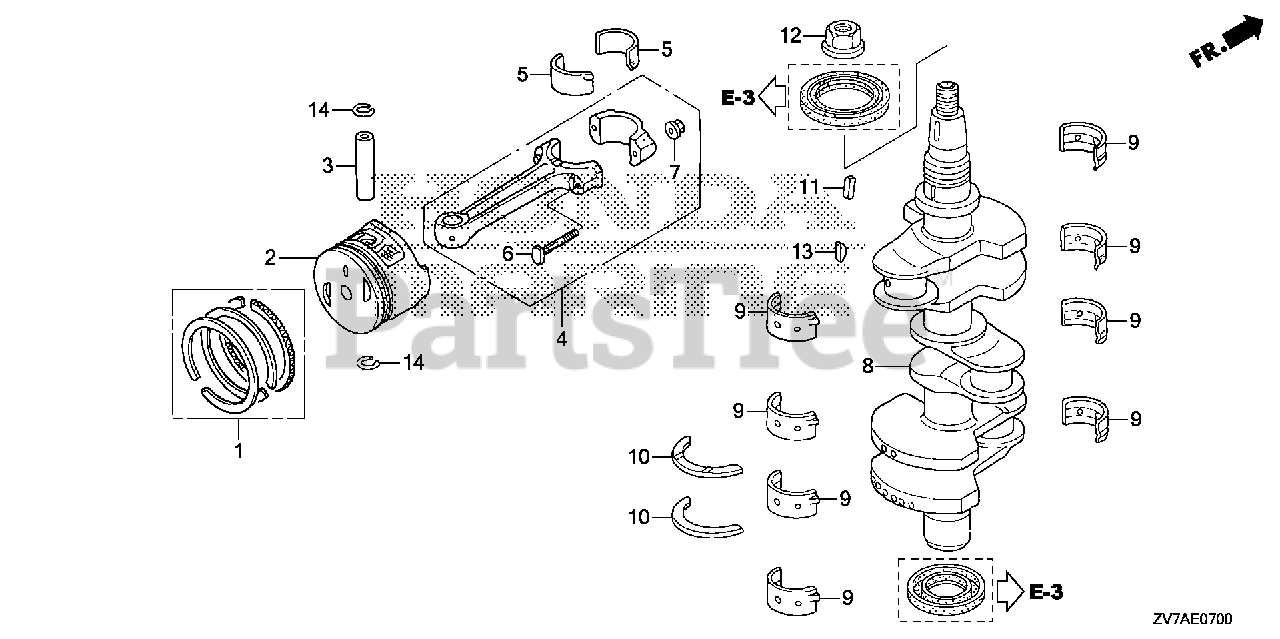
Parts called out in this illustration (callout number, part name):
1	RING SET, PISTON (STD)
3	PIN, PISTON
4	ROD SET, CONNECTING
5	BEARING A, CONNECTING ROD (BROWN)
5	BEARING B, CONNECTING ROD (GREEN)
5	BEARING C, CONNECTING ROD (YELLOW)
5	BEARING D, CONNECTING ROD (PINK)
5	BEARING E, CONNECTING ROD (RED)
6	BOLT, CONNECTING ROD
7	NUT, CONNECTING ROD
8	CRANKSHAFT
9	BEARING A, MAIN (17MM) (GREEN)
9	BEARING B, MAIN (17MM) (YELLOW)
9	BEARING C, MAIN (17MM) (PINK)
9	BEARING D, MAIN (17MM) (RED)
10	WASHER, THRUST
11	KEY, SPECIAL WOODRUFF (25X18)
12	NUT, SPECIAL (18MM)
13	KEY, SPECIAL (16X15)
14	CLIP, PISTON PIN (16MM)
